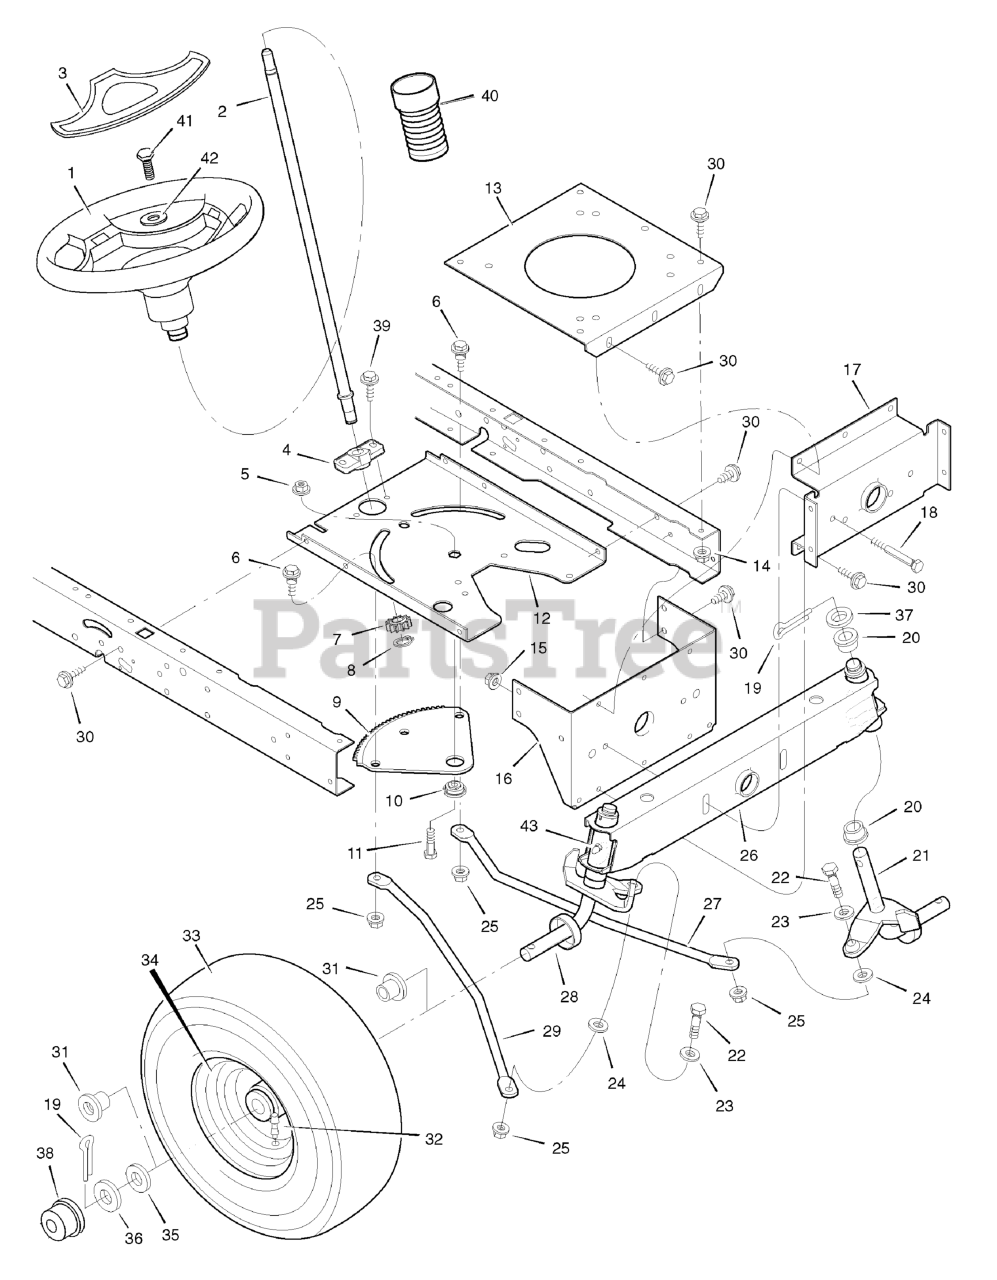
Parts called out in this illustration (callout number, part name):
1	WHEEL, Steering
2	POST, Steering
3	INSERT, Steering Wheel
4	BEARING, Lower
5	NUT, Flange
6	BOLT, Shoulder
7	GEAR, Pinion
8	RING, Snap
9	GEAR, Sector
12	PLATE, Steering
13	PLATE, Engine
14	NUT, Flange
15	NUT, Flange
16	BRACKET, Hanger
17	AXLE, Hanger
19	PIN, Cotter
21	SPINDLE ASSEMBLY, Left
25	NUT, Flange
26	AXLE ASSEMBLY
27	DRAG LINK, Left
28	SPINDLE ASSEMBLY, Right
29	Drag Link, Right
31	BEARING, Wheel
32	Stem, Valve
34	WHEEL & TIRE ASSEMBLY *
43	FITTING, Grease
